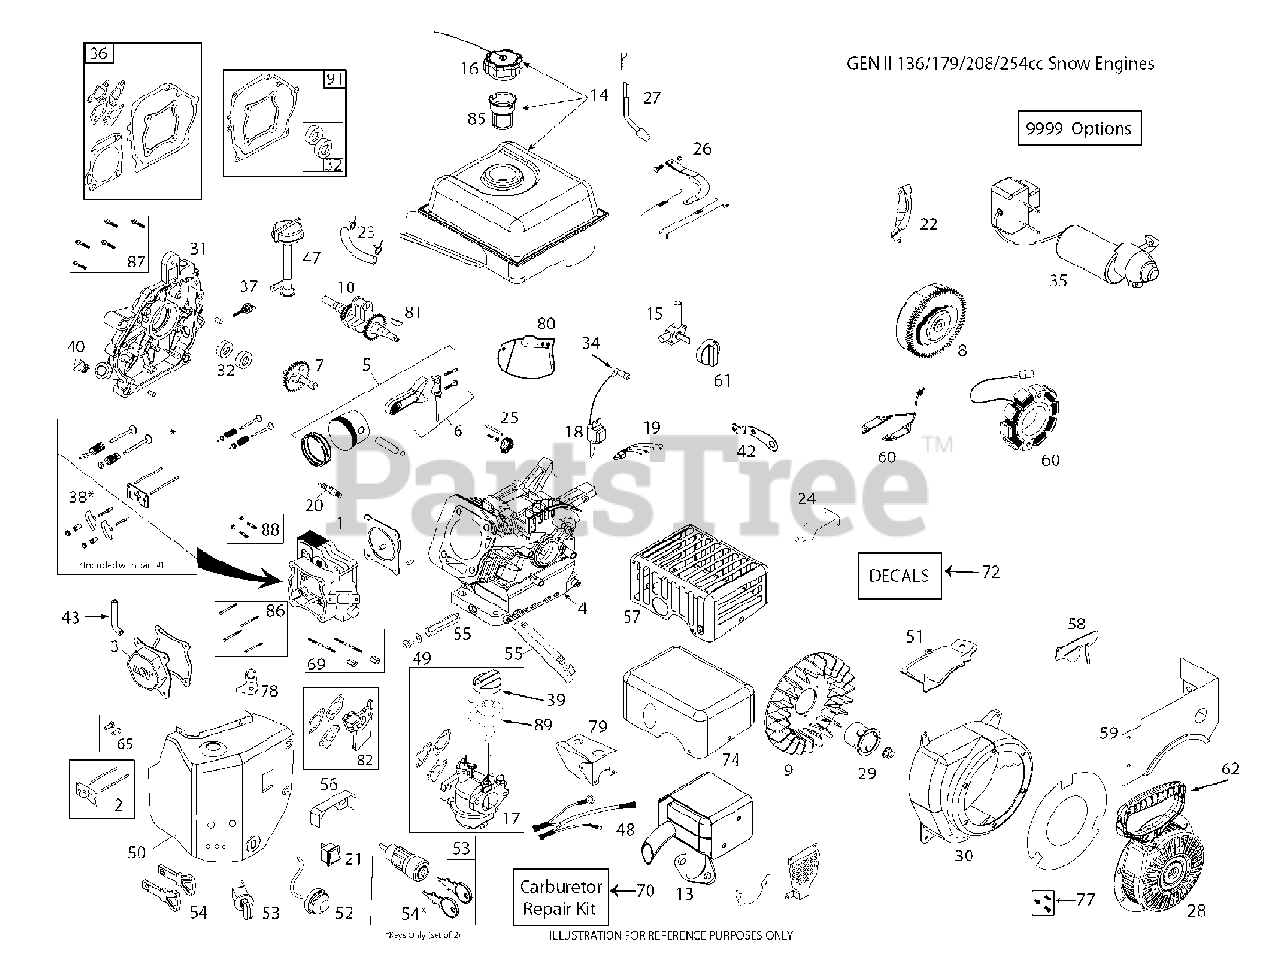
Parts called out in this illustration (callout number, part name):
1	CYLINDR.HEAD.SRV.KIT
2	KIT.PUSH.ROD.SRV(SK208-1001)
3	VALVE COVER ASSEMBLY
4	CYLINDER.ASM.SKSN0001.2
5	KIT.PISTON.SRV(SK208-1400)
6	KIT.CONNECT.ROD.SRV(SK208-1500
7	KIT.CAMSHAFT.208CC.LCT
8	FLYWHL.ASSY.ELECT.(SKSN0405)
9	KIT.COOLNG.FAN.SERV(SK208-4000
10	CRNKSHFT-KYD#14.208CCSKSNO8001
13	ASSY.MUFFLER.GENII.SKSN0201.1
14	FUEL.TK.ASSY.GENII.SKSN0311.1
15	FUEL.PETCOCK.SNOW(SKSN4900)
16	FUEL CAP OVERSIZED CLICK STYLE
17	CARB.ASSEMBLY.GEN.II.LCT.208CC
18	208CC IGN COIL (STD)
19	CDI.BOX SNOW
20	SPARK.PLUG(2083810)
21	SWITCH.ON/OFF(SKSN-0403)
22	SHLD.ELEC.START.FLY(SKSN-0605)
23	FUEL HOSE KIT
24	SPEED.CTRL.BRKT.(SKSN0150)
25	GOVENOR.GEARS ASM(SK2082900)
26	CARBURETTOR GOVERNOR LINK.ASM.
27	KIT.GOVERNOR.CRANK(SK208-3100)
28	RECOIL.STRT.ROUND(BLK) SNOW
29	STRTER.CUP(NON-SLOT)SKSN0601.2
30	BLOWER.HOUSING.ELEC.START.LCT
31	CRANKCASE.CVR.PRESS.IN.HI-OIL.
32	SEAL KIT (2 PCS)
34	SPARK.PLUG.BOOT.SNW,SKSN4691.1
35	STARTER.EL.230C.SNO.LCT.208CC.
36	GASKET.KIT.208CC(SK2084300.1)
37	DIPSTICK SMALL
38	ROCKER ARM KIT
39	CHOKE.KNOW.SNOW(SKSN4500)
40	NON REMOVABLE PLUG
42	Husqvarna TBD
43	TUBE.BREATHER.LCT.208
47	TUBE ASSY HIGH OIL-FILL
48	WIRE.HARNESS.SNOW
49	KIT.OIL.DRAIN.PLUG(SK2089911
50	HEATER.BOX.ASY-GEN2
51	SHIELD.CYLINGER.LCT.SKSN0608.1
52	PRIMER.BULB.WITH HOSE (SNOW)
53	SWITH.KEY.ASSEM.SNOW.SINGLE.ST
54	KEY SET(2 KEYS) SKSN0407.1
55	EXTENDED OIL DRAIN TUBE
56	SHIELD.VAPOR.SNOW
57	SHIELD.MUFFLER.CE.COMPLIANT
58	GOVERNOR.LINK.SHIELD PLATE
59	FUEL.TNK.SKRT.GENII.SKSN0103.1
60	CHARGING.COIL(ELEC)SKSN0406.1
61	FUEL KNOB-SNOW
62	STARTER.GRIP.SNOW.LCT.SKSN0603
65	TAPPET.KIT.LCT.208CC
69	CARB.STUDS & COUPLING KIT.SNOW
70	CARB.REPAIR.KIT.LCT.SK9900.2
72	Husqvarna TBD
74	COVER.MUFFLER.HEAT.SHIELD.
77	BOLT.KIT.RECOIL.LCT.ALL.ENGINE
79	COVER.CARBURETOR.SNOW
80	Husqvarna TBD
81	KEYS.FLYWHEEL.208/414CC.5PACK
82	SPACER.CARBURETOR.208CC.LCT
85	STRAINER.FUEL.TANK.LCT.208CC
86	KIT.BOLT.CYLINDER.HEAD.(4PC)
87	KIT.BOLT.CRANKCASE.COVER.6PC
88	STUD.MUFFLER.KIT.LCT
89	KNOB LCT.SKSN5325.1 SPEED
91	COVER CRANKCASE GASKET
9999	HIGH.ALTITUDE.JET.(>6,000FT)
